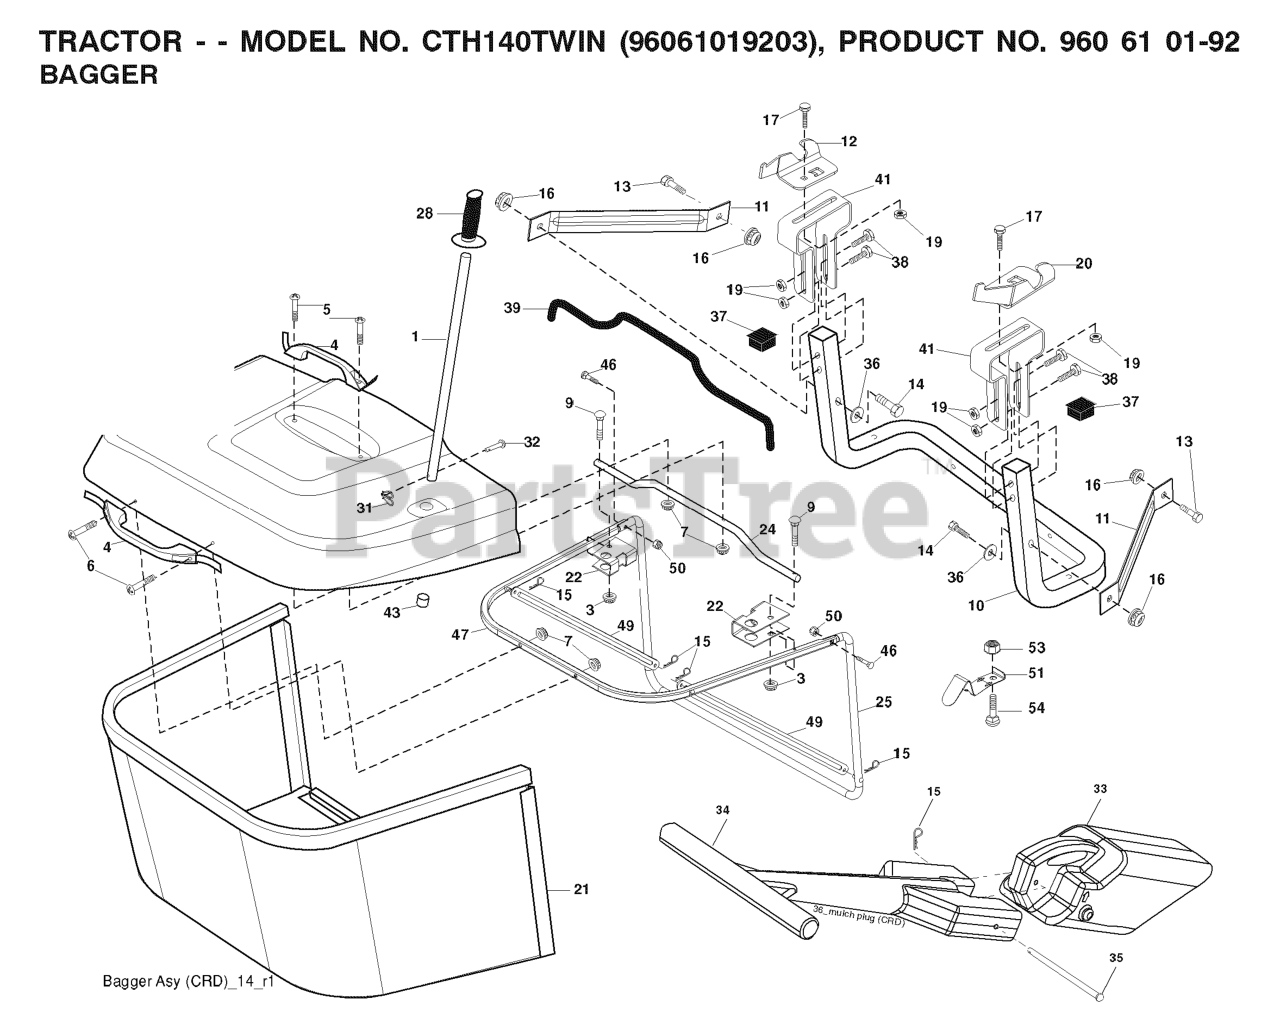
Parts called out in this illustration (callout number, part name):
1	TUBE HANDLE
3	NUT T
4	HANDLE.BAGGER.W/LVRS.BLK.CRD
5	SCREW.PAN.HEAD
6	REPL BY 532 75 00-29
8	COVER.PNT.BGR.CRD.WSLOTS.MS668
9	Bolt Carriage 1/4-20 x 2.25d x Gr.5
10	TUBE
11	BRACKET.SUPPORT.UPPER.BAG.CRD
12	BRKT PIVOT
14	BOLT-HEX EAK
15	RETAINER-SPRNG RB
16	NUT LOCK FLG 3/8-16 UNC
17	RP BOLT 5/16-18 X3/4 ZN/YEL GR
19	NUT LOCK HEX FLANGE 5/16-18
20	BRKT.PIVOT.RH.CRD
21	BAGGER.ASM.CRD.2007
22	BRKT.SIDE.BAG.CRD
24	TUBE.PIVOT.BAG.CRD.BLACK
25	PIPE
28	GRIP.HANDLE.BLACK
31	RETAINER CLIP
32	RIVET,DRILLED
33	PLUG.MULCHER.92 CRD
34	HANDLE.MULCHER.92.CRD (2 2)
36	WASHER
37	Plug Support Bagger CRD
38	BOLT.5/16-18X2.5
39	SEAL.BAGGER.CRD
41	BRKT.VERT.ADJ.BAGGER.CRD
43	PLUG, TUBING END
46	BOLT.CARRIAGE.5/16-18
47	PIPE
49	ROD
50	NUT.71038.31-18.HEX.NYLOCK
51	LATCH
53	NUT
54	BOLT
